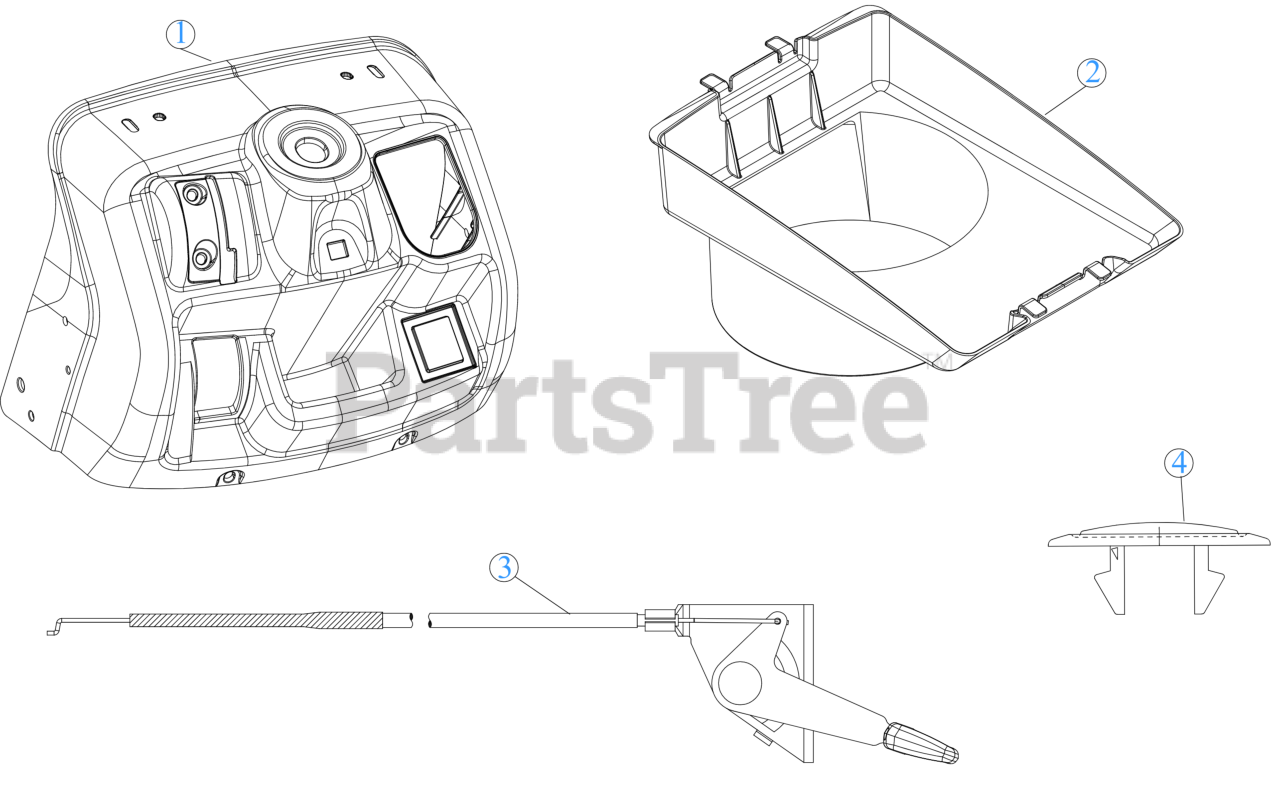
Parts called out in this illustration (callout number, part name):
2	HOOD PLENUM
3	THROTTLE CABLE 31" x 1.1
4	CHOKE PLUG
